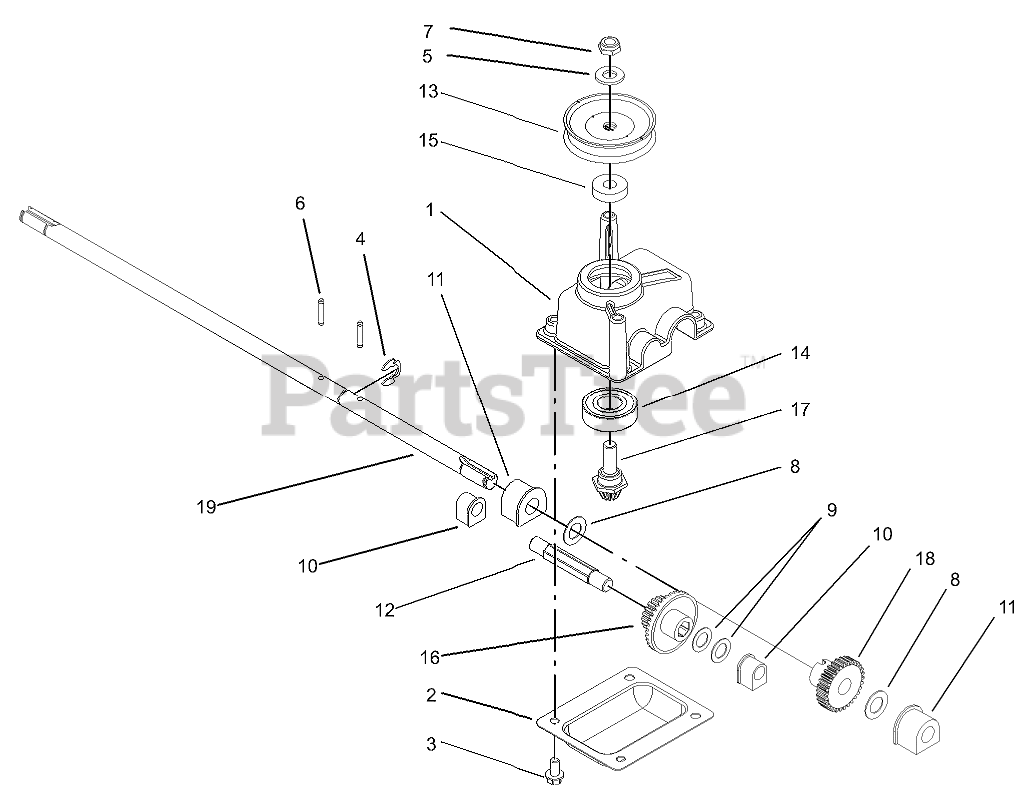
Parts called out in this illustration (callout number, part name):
1	CASE-GEAR
2	COVER-CASE, GEAR
3	SCREW-HWH
4	RING-RETAINING
5	WASHER-FLAT
6	PIN-GROOVE
7	NUT-HEX
8	WASHER-PLAIN
9	WASHER-THRUST
10	BUSHING
11	BUSHING
12	SHAFT-INTERMEDIATE
13	PULLEY-HALF
14	BEARING-BALL
15	SPACER
16	GEAR-19T SPUR, 37T BEVEL
17	GEAR-PINION, BEVEL
18	GEAR-30T
19	SHAFT-OUTPUT
